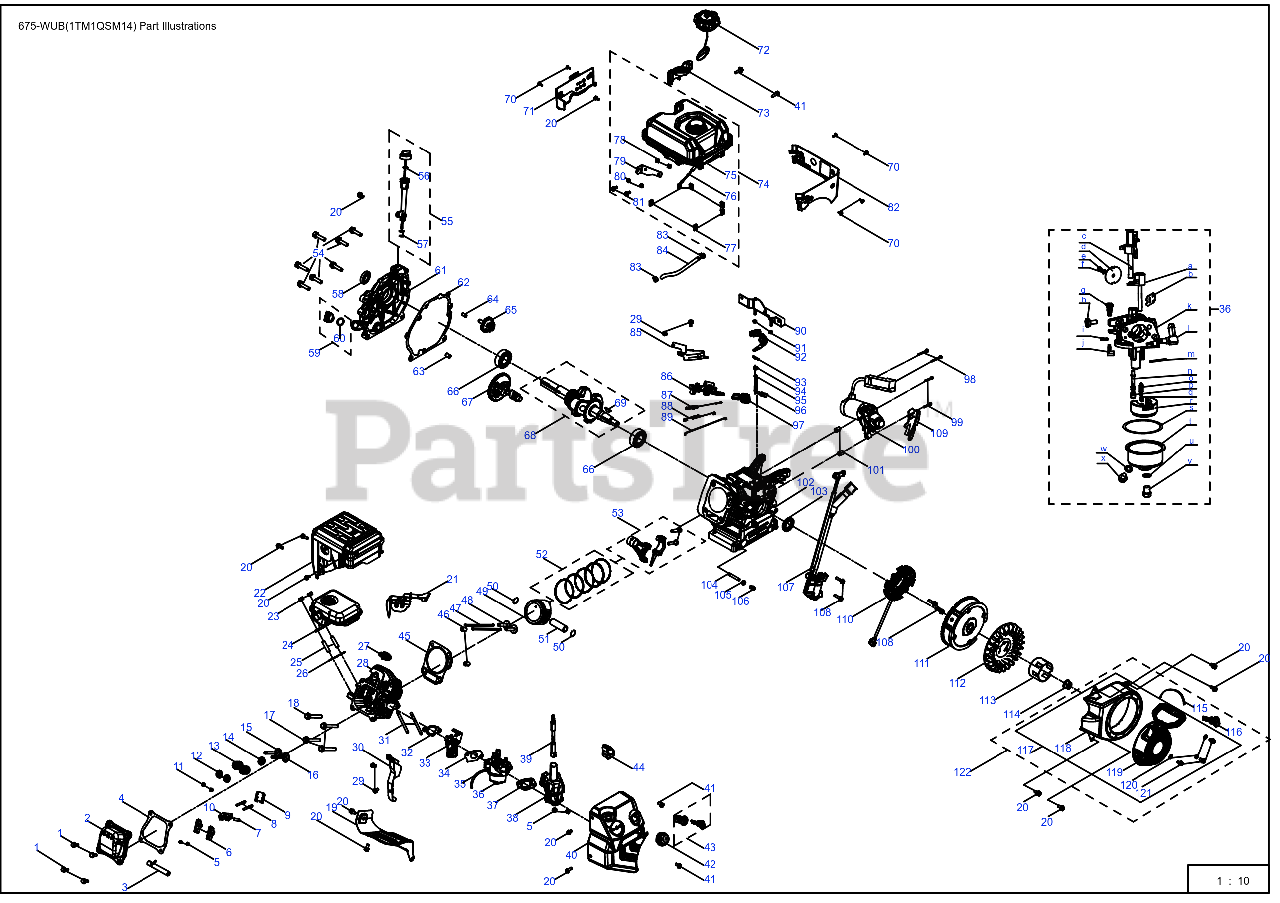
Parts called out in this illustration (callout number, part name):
1	BOLT M6 x 16
2	VALVE COVER
3	BREATHER HOSE
4	VALVE COVER GASKET
6	ROCKER ARM ASSEMBLY
7	ROCKER ARM SHAFT
8	PIVOT BOLT
9	PUSH ROD GUIDE
10	ROCKER ARM PIVOT BLOCK
11	EXHAUST VALVE ADJUSTER
12	EXHAUST VALVE SPRING RETAINER
13	VALVE SPRING
14	INTAKE VALVE SEAL
15	EXHAUST VALVE
16	INTAKE VALVE
17	SCREW M10-1.25 x 65 x GR10.9
18	BOLT M10-1.25 x 70
19	AIR SHIELD
20	BOLT M6-1 x 12 GR8.8
22	MUFFLER GUARD
25	STUD M8 x 36
26	MUFFLER GASKET
27	SPARK PLUG
28	CYLINDER HEAD
29	BOLT M6-1 x 12 GR8.8
30	SNOW GUARD
31	STUD M6 x 90
32	CARBURETOR INSULATOR GASKET
34	CARBURETOR GASKET
35	PRIMER HOSE
36	CARBURETOR ASSEMBLY 175SC
37	CARBURETOR GASKET PLATE
38	HEATER BOX
39	CHOKE LINKAGE
40	CONTROL PANEL
41	BOLT M6-1 x 18 GR8.8
43	ENGINE KEY SWITCH ASSEMBLY
44	CHOKE LEVER
45	CYLINDER HEAD GASKET
47	PUSH ROD (SINGLE)
50	PISTON PIN SNAP RING
51	PISTON PIN
52	PISTON RING SET
53	CONNECTING ROD ASSEMBLY
54	BOLT M8-1.25 x 32 GR5.8
55	DIPSTICK ASSEMBLY
56	DIPSTICK O-RING
57	OIL FILL TUBE O-RING
58	OIL SEAL
60	O-RING 15.8 x 2.5
61	CRANKCASE COVER
62	CRANKCASE COVER GASKET
63	DOWEL PIN
64	DOWEL PIN
65	GOVERNOR GEAR/SHAFT ASSEMBLY
66	BALL BEARING
68	CRANKSHAFT ASSEMBLY
69	FLYWHEEL KEY
70	BOLT: M5 x 14
71	FUEL TANK SHROUD (RH)
73	DECORATIVE COVER
75	FUEL TANK
76	FUEL FILTER
77	FUEL TANK MOUNT THREADED TAB
79	FUEL TANK MOUNT TAB
80	WASHER 6.5 x 1.5 x 12
81	BOLT M6 x 20
82	DECORATIVE SHEET (LH)
83	HOSE CLAMP
84	FUEL HOSE 6.3 x 12.5 x 162
85	GOVERNOR SHIELD
86	GOVERNOR GEAR BRACKET ASSEMBLY
87	GOVERNOR SPRING
88	THROTTLE RETURN SPRING
89	GOVERNOR ROD
90	FUEL TANK BRACKET
92	GOVERNOR LEVER
93	COTTER PIN
94	GOVERNOR SEAL
96	GOVERNOR SHAFT
97	THROTTLE KNOB
99	BOLT M6-1 x 32 GR8.8
100	ELECTRIC STARTER
101	DOWEL PIN
103	OIL SEAL
104	OIL DRAIN PIPE
105	WASHER
106	OIL DRAIN PLUG
107	IGNITION MODULE
108	BOLT M6-1 x 25 GR8.8
109	BLOWER HOUSING SHIELD
110	CHARGING COIL
112	COOLING FAN
113	STARTER CUP
114	FLYWHEEL NUT
115	CABLE TIE - 3 x 150
116	IGNITION KEY
117	RECOIL STARTER
118	BLOWER HOUSING
119	RECOIL STARTER ASSEMBLY
120	RECOIL FLAT WASHER
121	BOLT M6 x 10
